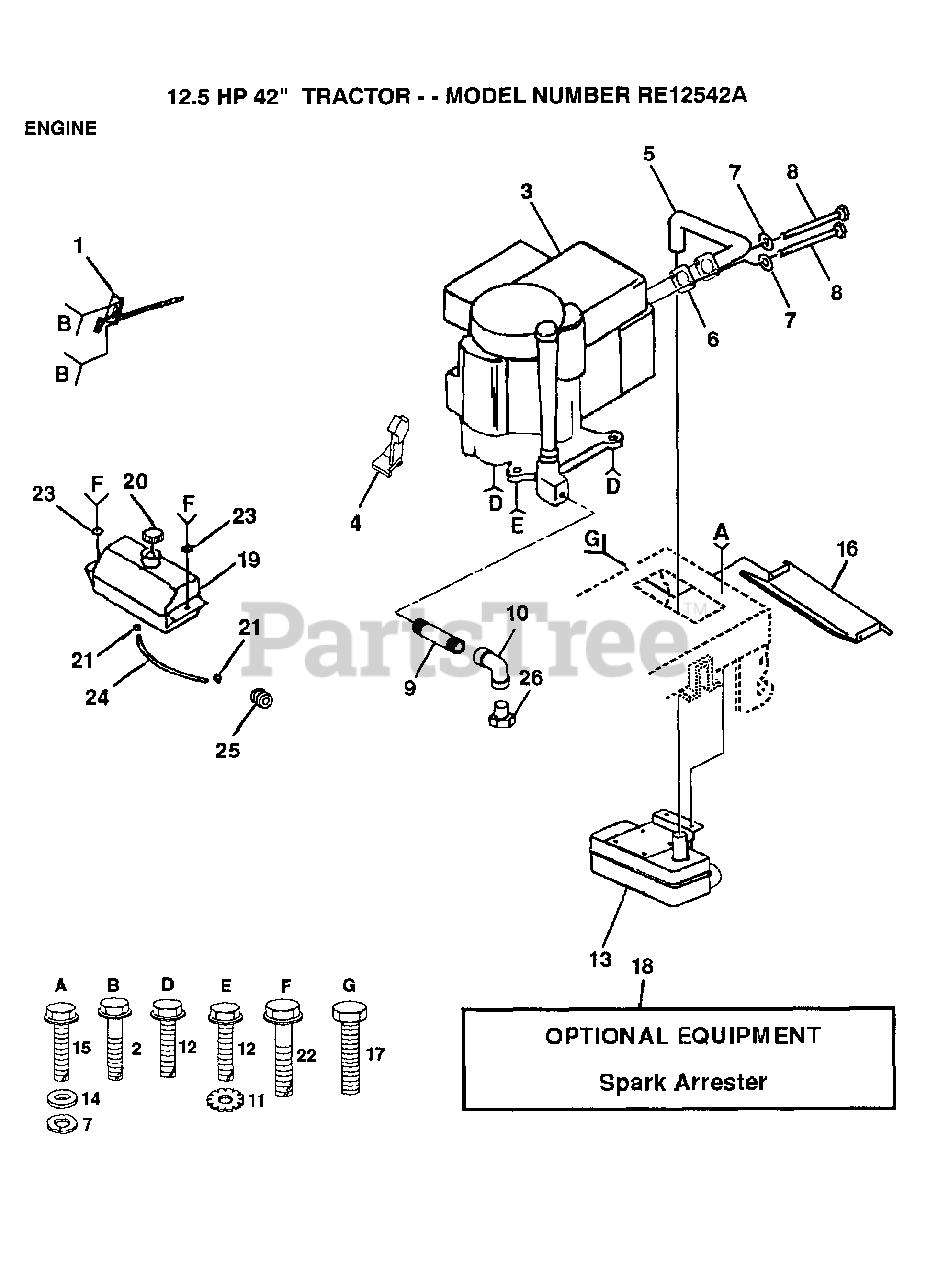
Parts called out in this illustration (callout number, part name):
2	SCREW LT
5	PIPE EXHAUST
7	LOCKWASHER
8	SCREW LT
9	PIPE NIPPLE
10	ELBOW
11	LOCKWASHER
12	SCREW
13	MUFFLER EUROPE
14	WASHER
15	SCREW
16	HEAT SHIELD
17	SCREW
18	SPARK ARREST KIT
19	TANK.FUEL.LT.
21	HOSE CLAMP
22	SCREW HEX CRT
23	WASHER
24	FUEL LINE T
